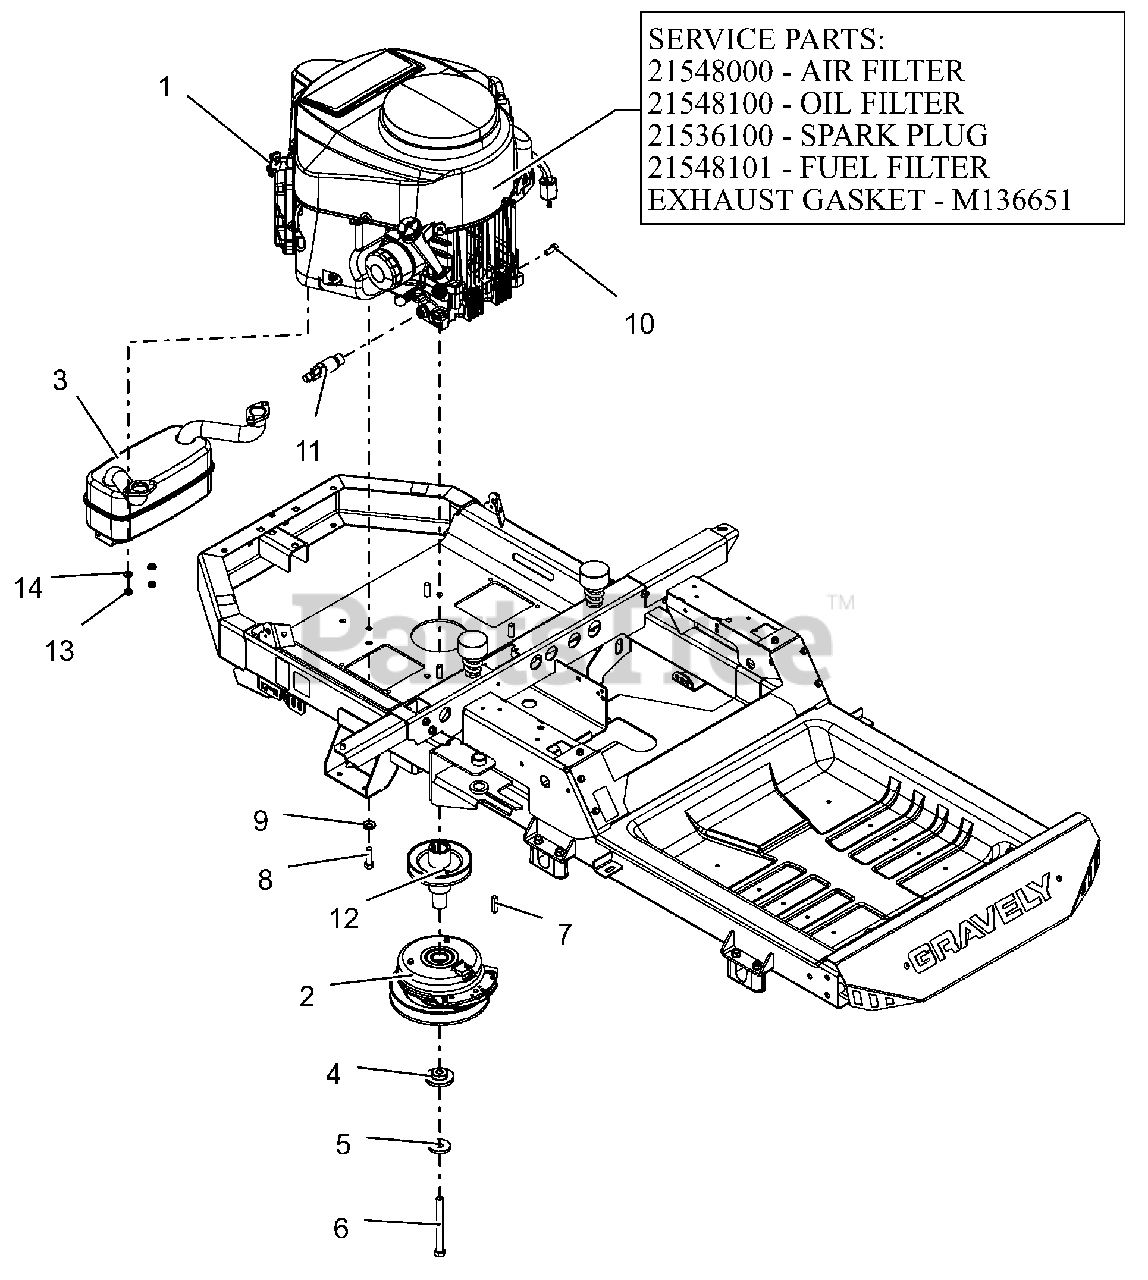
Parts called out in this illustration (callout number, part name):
1	ENGINE, KAWASAKI FR691 23HP
1	AIR FILTER, KAWASAKI FR
1	OIL FILTER, KAWASAKI FR
1	PLUG, SPARK
1	FUEL FILTER-KAWASAKI FR
1	GASKET, MUFFLER #
2	CLUTCH,105FTLB MONOPOLE 6.83"
3	MUFFLER - KAWASAKI
4	BSHG-FLG .469X1.06X.574X2.0
5	WASHER, 7/16" SPRING DISK
6	BLT, HEX .44-20X4.50 G8 ZCC NT
7	KEY-SQ .25 X 1.25 X .25 SAE
8	BLT, HEX .38-16X1.25 G5 ZCC NT
9	WASHER, 3/8" SPRING DISC
10	BLT, HEX M8-1.25X20 G8.8 ZCC
11	DRAIN, OIL M20X2.5
12	WLDMT, DRIVE SHEAVE-X
13	NUT,NYL M8-1.25 G8.8 ZCC
14	WSHR,LK-REG .312X.078 ZCC
